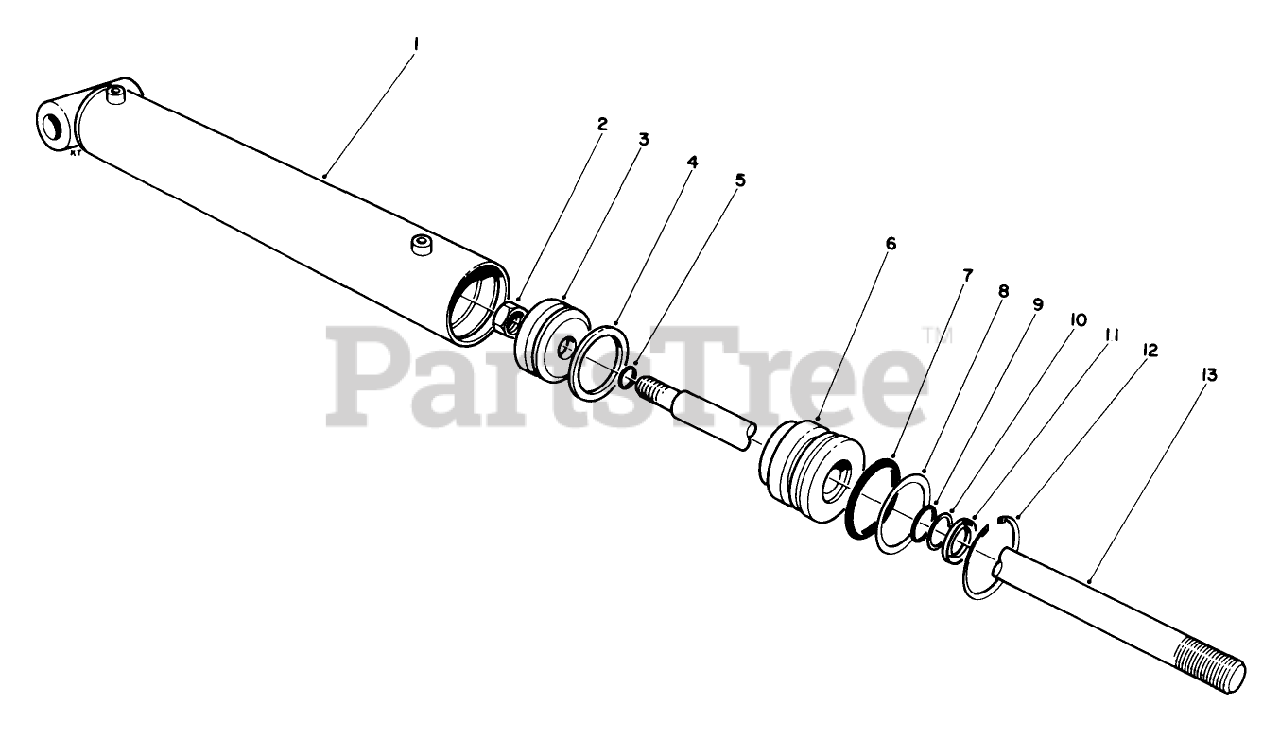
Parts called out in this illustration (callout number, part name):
1	Barrel
2	LOCKNUT
3	PISTON
5	"O" Ring
7	"O" Ring
9	"O" Ring
11	Dust Seal
12	RING-RETAINING
13	SHAFT
